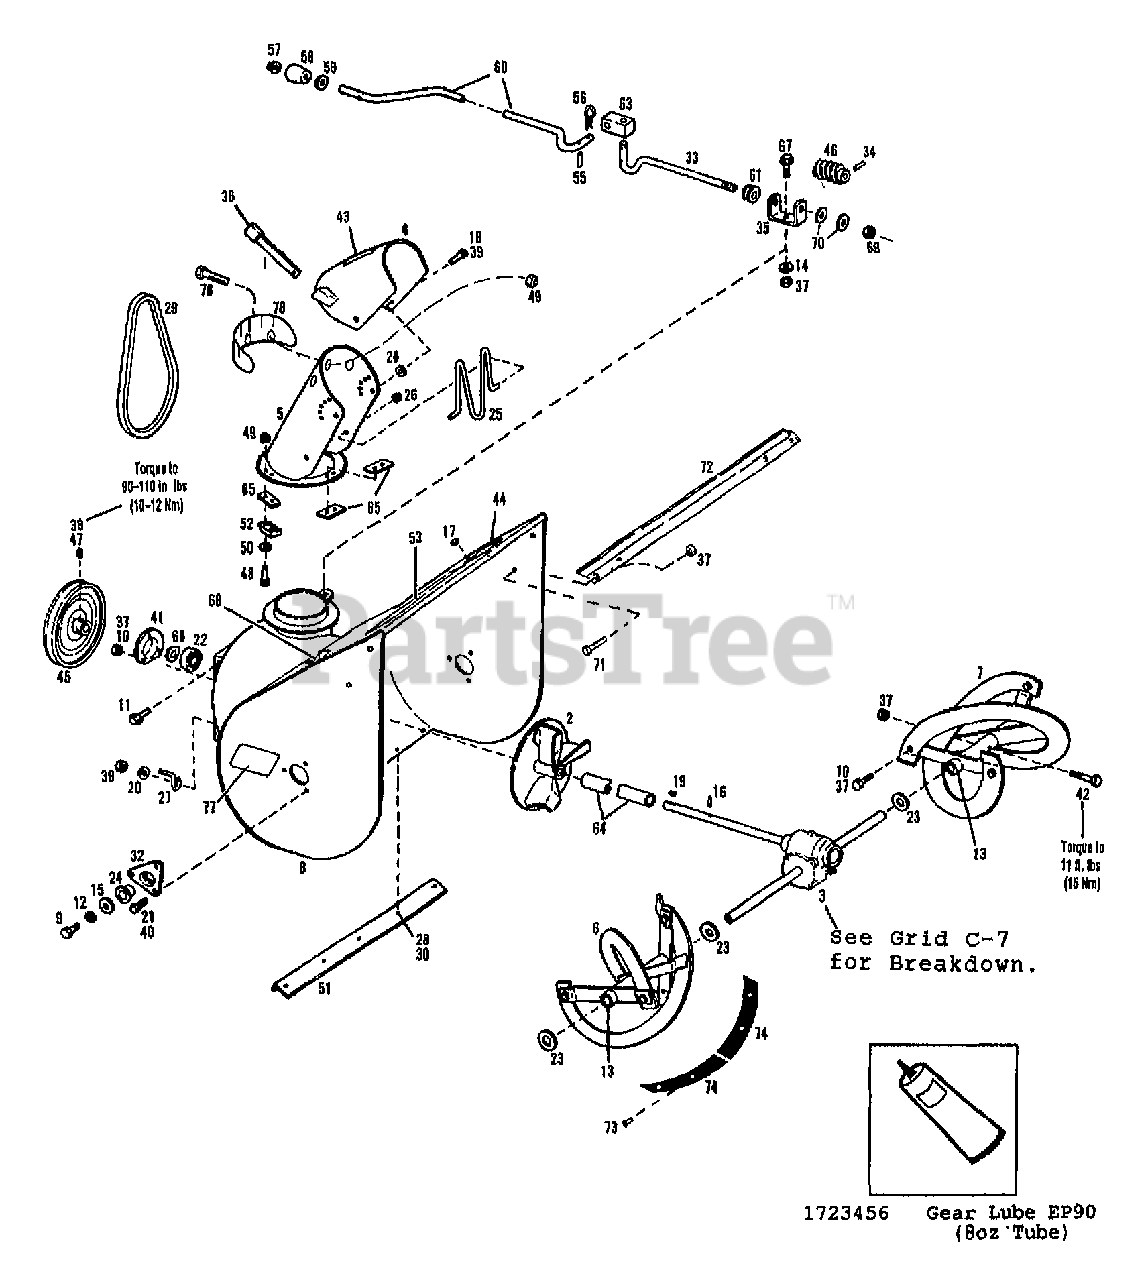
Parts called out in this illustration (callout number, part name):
1	LEVER-ADJUSTING
2	ASSM-IMPELLER
3	ASSM-GEAR CASE
4	CAP-DISCH
5	ASSM-CHUTE
6	AUGER-W/PAD RH
7	AUGER-W/PAD LH
8	HOUSING-AUGER W/DECAL
9	SCR-HH 1/2-13X.75 G5 ZP
10	SCR-HH 5/16-18X.63 G5
11	SCR-HFLK 5/16-18X.75
12	WASHER-LK .5
13	SUPPORT-AUGER
14	WASHER-FLAT 5/16 SAE
15	WASHER-1/2 FLAT
16	PIN-ROLL 1/4 X 1-1/4
18	SCR-HH 3/8-16X.75 G5 ZP
19	KEY-HI PRO .187X.75
20	WASHER-FLAT 3/8 SAE
21	SCR-HH 1/4-20X.625 G5 ZP
22	BEARING-BALL
23	WASHER-SPEC
24	BUSHING-FLANGE
25	GUARD-CHUTE
26	NUT-PUSH 3/16
27	GUIDE-BELT
28	NUT-HFLK 5/16-18 ZP
29	BELT-V 36.00
30	SCR-CARR 5/16-18X.50 G5 ZP
32	SUPPORT-BEARING
33	SHAFT-CHUTE CONTROL
34	PIN-DRIVE .09X.75
35	SUPPORT-GEAR
36	GRIP-VACUCUT
37	NUT-TOP/LK 5/16-18 ZP
38	SCR-SET SQ 5/16-18X5/8
39	NUT-LOCK 3/8-16
40	NUT-HT LK 1/4-20
41	RETAIN-BEARING
42	SCR-SHEAR 5/16-18X1.75
43	DECAL-WARNING
44	DECAL-WARNING
45	SHEAVE-AUGER DRIVE
46	GEAR-WORM LH
47	LOCTITE-242 (.5 ML TUBE)
48	SCR-HW M10-24X.88 EXTTOOTH
49	NUT-H/LK M10-24 NYLOCK
50	WASHER-.505X.22X.05
51	BLADE-SCRAPER
52	CLIP-HOLD DOWN
53	DECAL-LOGO
55	PIN-ROLL 1/8 X 3/4
56	PIN-CLIP .08
57	NUT-PUSH 3/8 ZP
58	KNOB
59	WASHER-FLAT .375DIA
60	CRANK-CHUTE CONTROL
61	BUSHING-NYLON
63	BLOCK-SWIVEL NYLON
64	SLEEVE
66	SHIM-1.75X1.26X.02
67	SCR-HFLK 5/16-18X.75 ZP
68	DECAL-AMERICAN LEGEND-SM
69	NUT-HF/LK 3/8-16
70	BUSHING-NYLON
71	SCR-HHC 5/16-18X.75 GR 5 ZP
72	KIT-SLICER DRIFT (2)
73	RIVET-POP
74	KIT-AUGER PAD (4 PER UNIT)
76	SCR-TR HD 10-24X.375
77	DECAL-HOUSING SIDE
78	DEFLECTOR-CHUTE
